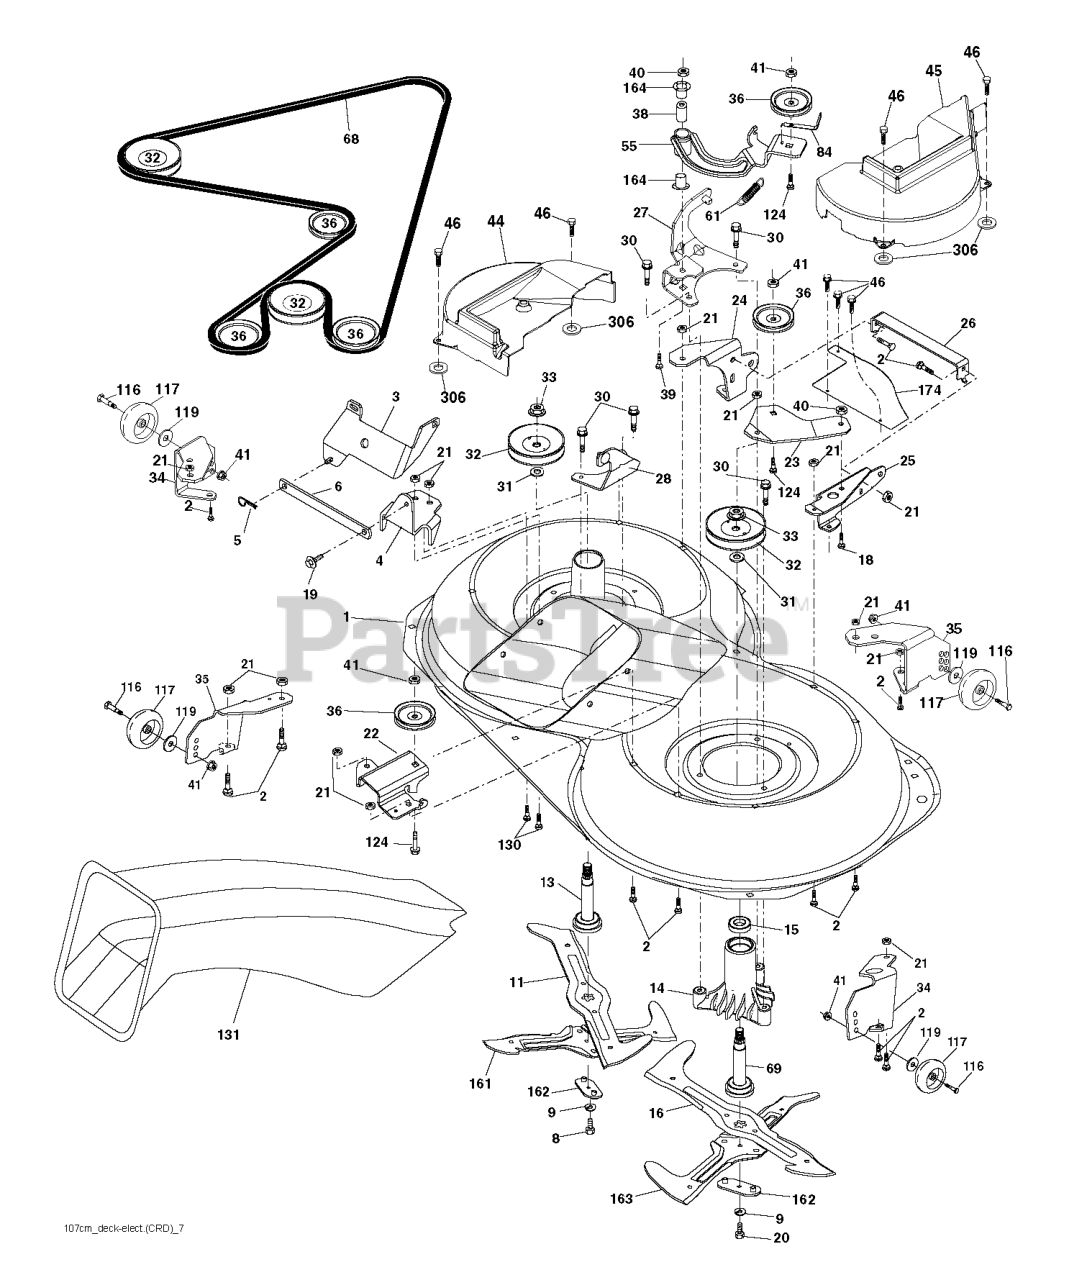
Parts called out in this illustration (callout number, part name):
1	Housing Asm. Mower 107 CRD
2	RP BOLT 5/16-18 X3/4 ZN/YEL GR
5	RETAINER-SPRNG RB
6	BAR.SWAY.92.CRD
8	BOLT.3/8-24X1.25 GR8
9	LOCKWASHER
11	BLADE.3N1.LH.CRD
13	SHAFT ASM VENT
14	HOUSING.MANDREL.VENTED (MACHD)
16	BLADE.3N1.RH.CRD
19	BOLT SHD 5/16-18
20	BOLT.3/8-24X1.25GR8. LHTHRD
21	LOCKNUT
22	BRACKET.IDLER.RR.107.CRD
24	BRACKET
25	BRACKET RF
26	SUPPORT
28	BRACKET
30	SCREW, WASHER HEAD
31	WASHER.SPACER.MANDREL
32	PULLEY.MANDREL.4.80 PD.2006
33	NUT.FLANGE.LOCK.TOP
34	BRACKET
35	BRACKET
36	PULLEY.IDLER.4.25
41	NUT LOCK FLG 3/8-16 UNC
46	SCREW.1/4-20X5/8
55	ARM.IDLER.107.CRD
61	SPRING
68	HEX-BELT 107 MOWER
69	SHAFT.ASM.W/LWR.BRG.RH.THREAD
84	KEEPER, BELT IDLER
116	BOLT.SHOULDER.3/8-16X3-5/8.
117	RP WHEEL. GUAGE RALLY
119	WASHER
124	BOLT.3/8-16X1.50
130	BOLT.CARR.SQNK.5/16-18UNC.X3/4
131	CHUTE BAGGER
163	BLADE.CROSS.RH.CRD.107
164	BRNG T
174	PLATE
306	PALNUT 1/4
